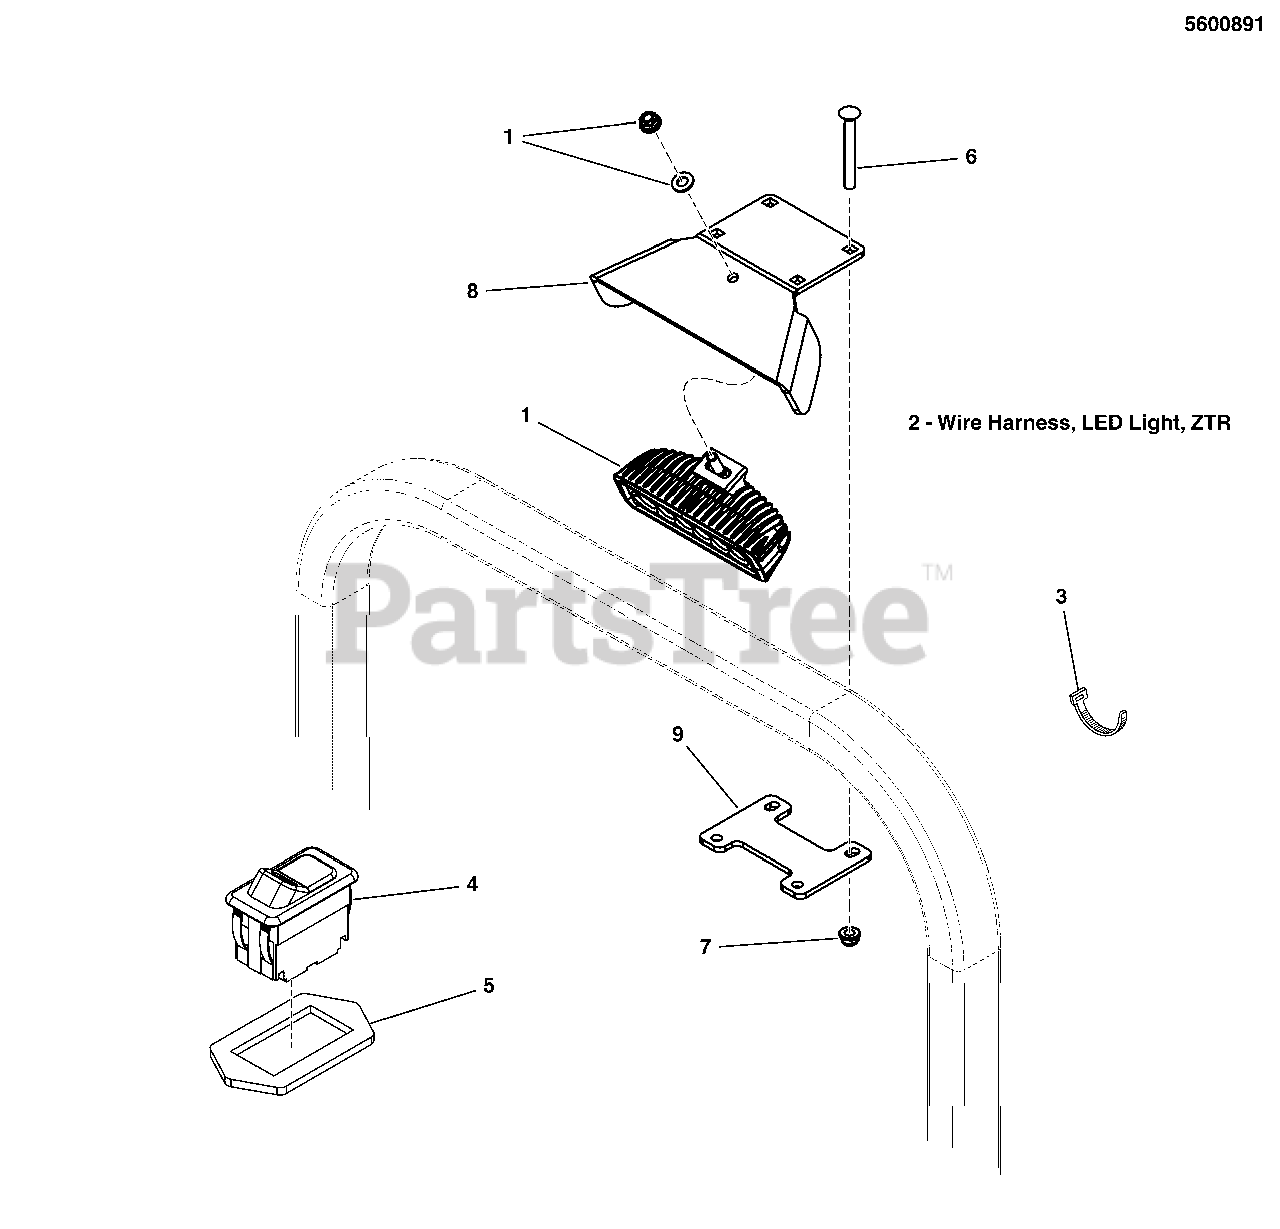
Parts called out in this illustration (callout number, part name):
1	LED HEAD LIGHT & HARDWARE
2	WIRE HARNESS, LED LIGHT, ZTR
3	TIE, SELF-LOCKING, 12"
4	SWITCH, HEADLIGHT
5	RING, SWITCH RETAINER
6	BOLT, 5/16-18 X 2-3/4, CARRIAGE, GD5, CZ
7	NUT, 5/16-18 HEX NYLOCK FLANGE
8	PLATE, LIGHT KIT MOUNT, ROPS - BLK
9	PLATE, LIGHT KIT SUPPORT - BLK
